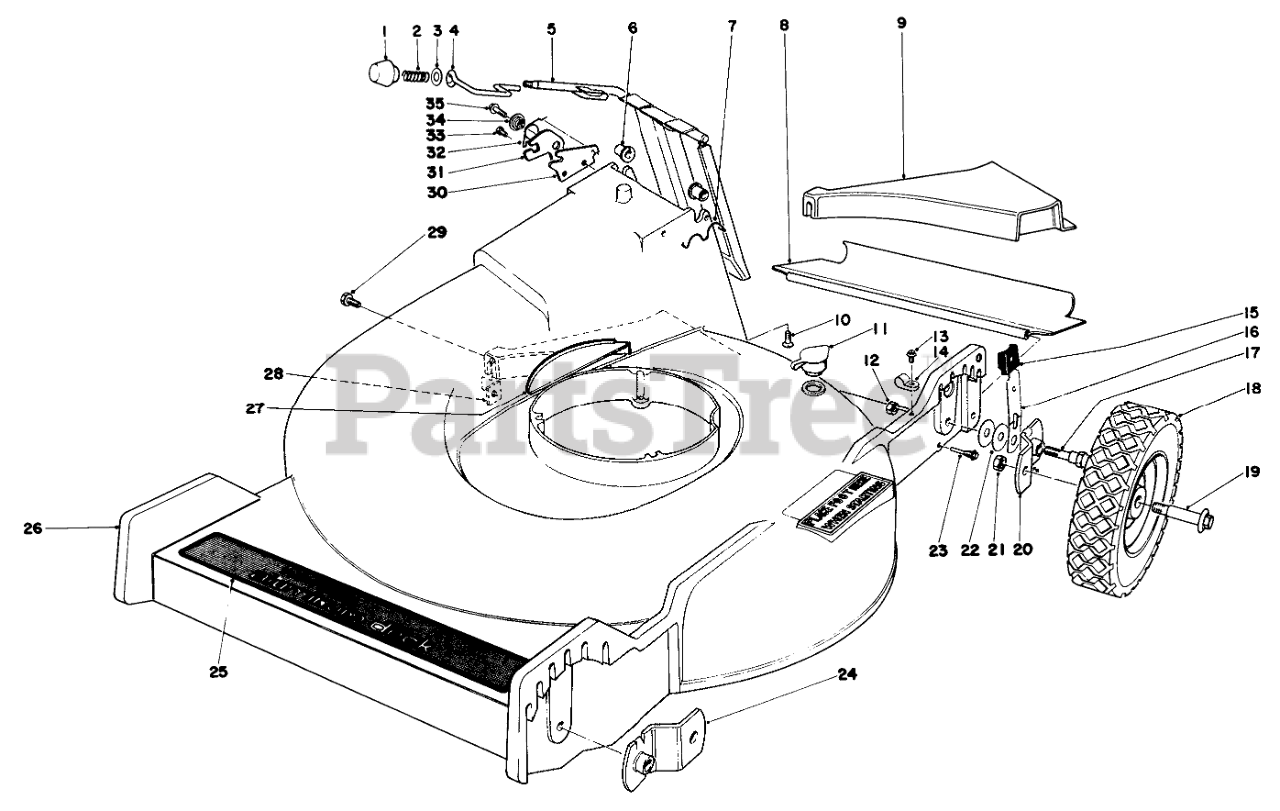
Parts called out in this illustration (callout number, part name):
2	COMPRESSION SPRING
3	WASHER
4	DOOR LATCH
5	Door Handle
6	BUSHING-NYLON
7	Door Retainer
8	REAR SAFETY SHIELD
9	Insert Rear
10	SCREW-HH
11	WASHOUT PLUG
12	Nut
13	SCREW
14	CABLE CLAMP
15	KNOB-ARM
16	SPRING ARM ASM
17	PIVOT SCREW
18	Wheel Assembly
20	PIVOT ARM ASM A
21	Nut
22	WASHER-PIVOT
23	SAFTEY SHIELD SCREW
24	PIVOT ARM ASM B
25	Decal-Front
26	Housing
27	HOUSING CAP
28	SPECIAL NUT
29	SCREW THD 1/4 20 5/8
30	DOOR LATCH PLATE
31	Latch Safety
32	TORSION SPRING
33	SCREW-HWH
34	Latch Spacer
35	Screw
